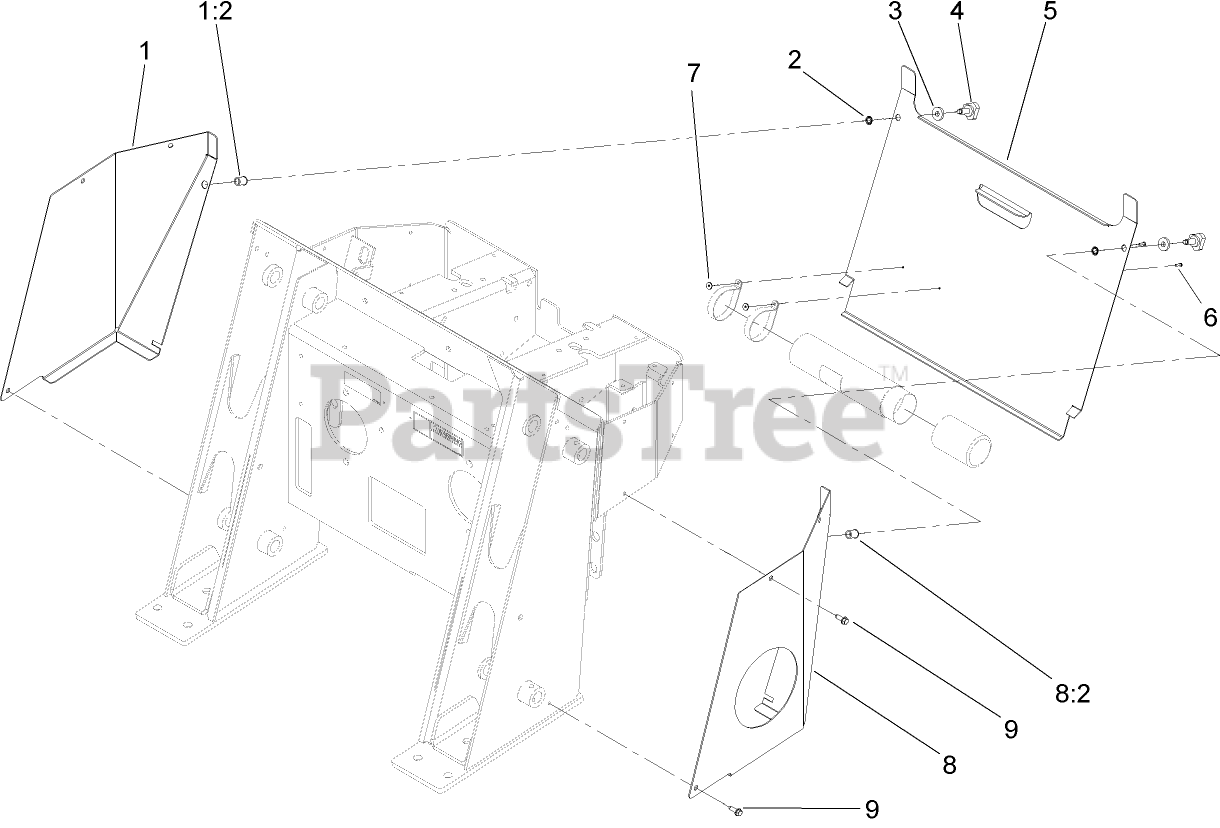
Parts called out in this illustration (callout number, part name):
1	RH REAR COVER SUPPORT ASM
1:2	INSERT-NUT
2	RING-RETAINING
3	WASHER-RUBBER
5	COVER-ACCESS, REAR
6	RIVET-POP
7	WASHER-BACK
8	LH REAR COVER SUPPORT ASM
8:2	INSERT-NUT
9	SCREW-HWH, THREAD ROLL
